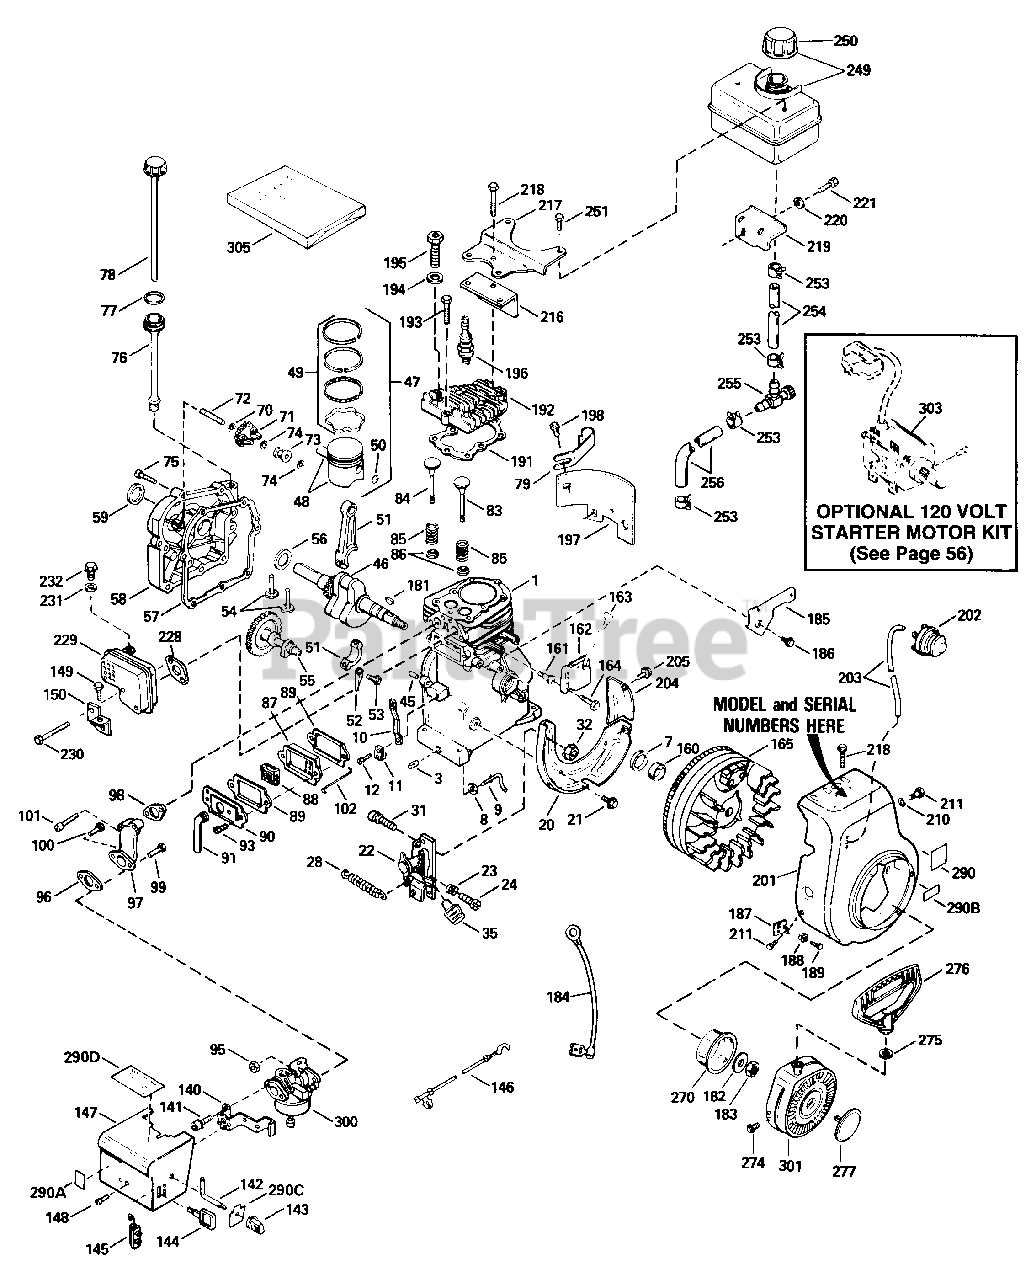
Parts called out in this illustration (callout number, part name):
1	Cylinder Ass'y.
3	Plug, Pipe, l/4-18
7	Seal, Oil
8	Washer, Flat
9	Rod, Governor
10	Lever, Governor
11	Clamp, Governor Lever
12	Screw, Hex Washer Hd., 8-32 x 5/16
20	Baffle, Blower Housing
21	Screw, Hex Washer Hd. Durlok, 1/4-20 x 5/8
22	Control Ass'y., Bracket
23	Spring, Compression
24	Screw, Fil. Hd., 5-40 x 7/16
28	Spring, Extension
31	Screw, Fil. Hd. Sems, 8-32 x 1/2
32	Nut, Lock, 8-32
35	Knob, Speed Control
45	Pin, Dowel
46	Crankshaft Ass'y.
47	Piston, Pin & Ring Ass'y. (Std.)
47	Piston, Pin & Ring Ass'y. (.010 Oversize)
47	Piston, Pin & Ring Ass'y. (.020 Oversize)
48	Piston & Pin Ass'y. (Std.)
48	Piston & Pin Ass'y. (.010 Oversize)
48	Piston & Pin Ass'y. (.020 Oversize)
49	Ring Set, Piston (Std.)
49	Ring Set, Piston (.010 Oversize)
49	Ring Set, Piston (.020 Oversize)
50	Ring, Piston Pin Retaining
51	Rod Ass'y., Connecting
52	Dipper, Oil
53	Bolt, Connecting Rod
54	Lifter, Valve
55	Camshaft (Compression Release)
56	Washer, Thrust
57	Gasket, Cylinder Cover
58	Cover, Cylinder
59	Seal, Oil
70	Washer, Flat
71	Gear, Governor
72	Shaft, Mechanical Governor
73	Spool, Governor
74	Ring, Retaining
75	Screw, Hex Hd. Sems, 1/4-20 x 1 1/4
76	Tube Ass'y., Oil Fill
79	Clip, Oil Fill
83	Valve, Exhaust (Std.)
83	Valve, Exhaust (1/32" Oversize)
84	Valve, Intake (Std.)
84	Valve, Intake (1/32" Oversize)
85	Spring, Valve
86	Cap, Valve Cover
87	Body, Valve Cover
88	Element, Valve Body
89	Gasket, Valve Cover
90	Cover, Breather
91	Tube, Breather
93	Screw, Fil. Hd. Sems, 10-24 x 1/2
95	Nut & Lock Washer Ass'y. 1/4 - 28
96	Gasket, Carburetor
97	Pipe, Intake
98	Gasket, Intake
99	Screw, Hex Hd., 1/4 - 28 x 7/8
100	Screw, Hex Hd., 1/4-28 x 1-11/16
101	Screw, Fil. Hd. Sems, 1/4 - 20 x 1 - 19/32
102	Link, Governor to Throttle
140	Bracket, Choke
141	Screw, Fil. Hd. Sems, 10 - 32 x 1/2
142	Rod, Choke
143	Knob, Choke Control
144	Key, Ignition
145	Terminal Ass'y.
146	Wire, Ground
147	Cover, Carburetor
148	Screw, Pan Hd. Sems, 8-32 x 5/16
149	Screw, Hex Hd. Sems, Taptite, 10 -24 x 3/8
150	Bracket, Carburetor Cover
160	Spacer, Flywheel Key
161	Stud, Solid State Mounting
162	Solid State Ass'y.
163	Cover, Spark Plug
164	Screw, Hex Hd. Sems, 10-24 x 1
165	Flywheel (w/Ring Gear)
181	Key, Flywheel
182	Washer, Belleville
183	Nut, Flywheel
184	Wire, Ground
185	Bracket, Hold Down
186	Screw, Hex Washer Hd. Self-Tap Sems, 10-24 x 9/16
187	Bracket, Grommet Mounting
188	Grommet, Plastic
189	Screw, Pan Hd. Taptite, 8-32 x 3/8
191	Gasket, Cylinder Cover
192	Head, Cylinder
193	Screw, Hex Flanged Hd., 5/16-18 x 1 1/2
194	Washer, Flat
195	Screw, Special Hex Hd., 5/16-18 x 1 1/2
196	Plug, Spark
197	Extension, Blower Housing
198	Screw, Fil. Hd. Sems, 10-24 x 1/2
201	Housing, Blower
202	Primer Ass'y.
203	Line, Primer
204	Extension, Baffle
205	Screw, Hex Washer Hd. Shakeproof Self-Drilling, 8-18 x 7/16
210	Washer, Flat
211	Screw, Hex Hd. Sems, 1/4-28 x 7/16
216	Baffle, Heat
217	Plate, Fuel Tank
218	Screw, Hex Flange Hd., 5/16-18 x 2
219	Bracket, Fuel Tank Mounting
220	Washer, Flat
221	Screw, Hex Hd. w/Belleville Washer, 1/4-20 x 11/16
228	Gasket, Exhaust
229	Muffler
230	Screw, Fil. Hd. Sems, 1/4-20 x 2 1/2
231	Washer, Flat
232	Screw, Hex Washer Hd. Sems, 1/4-20 x 1/2
249	Tank Ass'y., Fuel
250	Cap, Fuel Tank
251	Screw, Hex Washer Hd. Self-Tap Sems, 1/4-15 x 7/8
253	Clamp, Fuel Line
254	Line, Fuel
255	Valve, Shut-Off
256	Line, Fuel
270	Cup, Starter
274	Screw, Hex Wash. Hd. Self-Tap Sems, 1/4 - 15 x 7/8
275	Washer, Flat
276	Handle, Starter
277	Plug, Starter
290	Decal, Name
290A	Decal, Instruction
290B	Decal, Primer
290C	Decal, Choke
290D	Decal, Warning
300	Carburetor
301	Starter, Rewind
303	Electric Starter Kit (Optional)
305	Gasket Set
